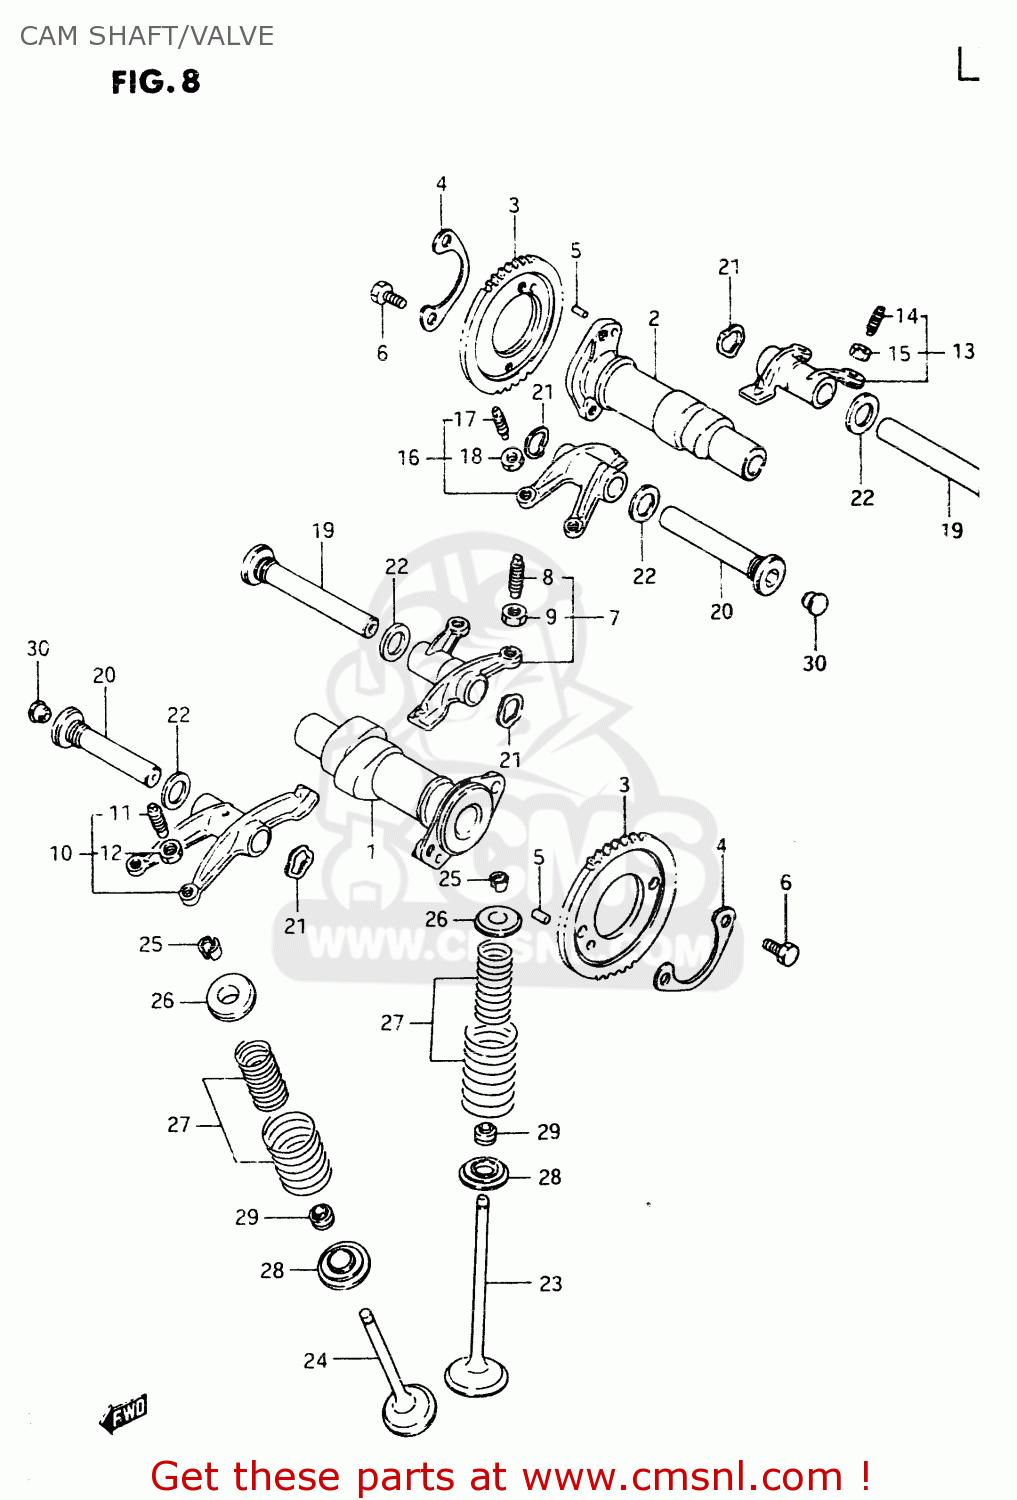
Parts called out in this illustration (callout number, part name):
1	CAMSHAFT,FR
2	CAMSHAFT,RR
3	SPROCKET,CAMSHAFT(NT:42)
4	WASHER,CAM CHAIN SPROCKET
5	PIN
6	BOLT(6X12.5)
7	ARM COMP,INTAKE VALVE ROCKER
8	SCREW,TAPPET ADJUSTING
9	NUT,ADJUSTING SCREW
10	ARM,EXHAUST VALVE ROCKER FR
11	SCREW,TAPPET ADJUSTING
12	NUT,ADJUSTING SCREW
13	ARM,INTAKE VALVE ROCKER RR
14	SCREW,TAPPET ADJUSTING
15	NUT,ADJUSTING SCREW
16	ARM,EXHAUST VALVE ROCKER RR
17	SCREW,TAPPET ADJUSTING
18	NUT,ADJUSTING SCREW
19	SHAFT,INTAKE VALVE ROCKER ARM
20	SHAFT,EXHAUST VALVE ROCKER ARM
21	WASHER
22	GASKET(13.8X18.8X4.8) (NAS)
23	VALVE,INTAKE
24	VALVE,EXHAUST
25	COTTER,VALVE
26	RETAINER,VALVE SPRING
27	SPRING SET,VALVE
28	SEAT,VALVE SPRING
29	SEAL,OIL(5.5X11X8.2)
30	CAP(OD:10)
